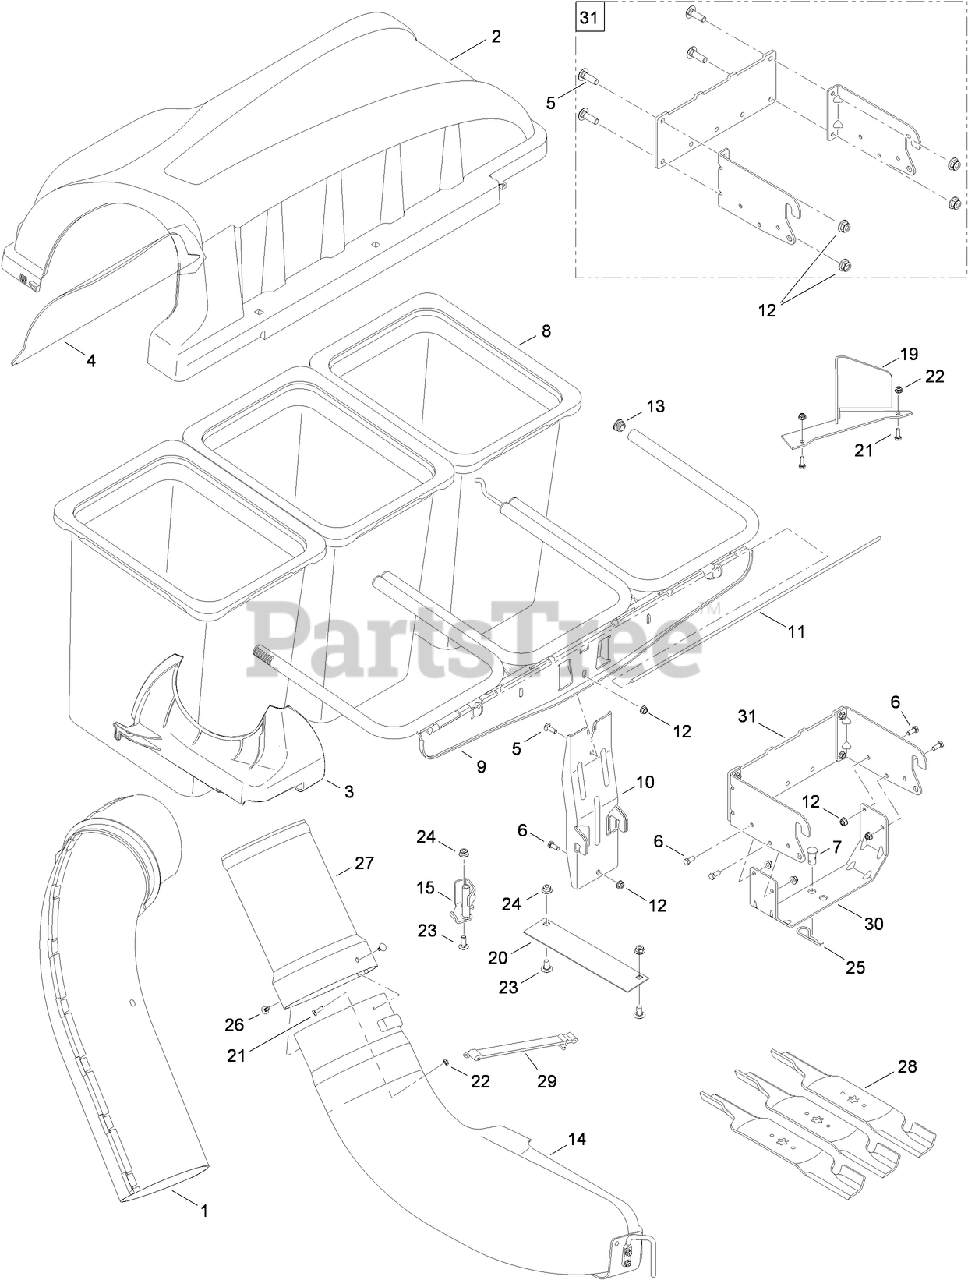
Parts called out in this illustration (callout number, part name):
1	UPPER CHUTE ASM
2	TRIPLE BAGGER COVER ASM
3	SUPPORT-CHUTE, UPPER
4	SCREEN-COVER, BAGGER
5	BOLT-CARR
6	SCREW-HH
7	PIN-CLEVIS
8	GRASS BAG ASM
9	TRIPLE BAG SUPPORT ASM
10	BRACKET-SUPPORT, VERTICAL
11	PIN-HINGE, COVER
12	NUT-LOCK, FLANGE
13	PLUG-END
14	ELBOW-CHUTE, DISCHARGE
15	BRACKET-STOP, CHUTE
19	Baffle-Deck
20	PLATE-CHUTE, DISCHARGE
21	SCREW-HH
22	NUT-LOCK, FLANGE
23	BOLT-CARRIAGE
24	NUT-LOCK, FLANGE
25	CLIP-HAIRPIN
26	CLIP-RATCHET, FASTENER
27	ADAPTER-CHUTE, BAGGER
28	BLADE-BAGGING (STAR, 17.90 INCH)
29	STRAP-CHUTE
30	SUPPORT-BRACKET, UNIVERSAL
31	HITCH BRACKET ASM
